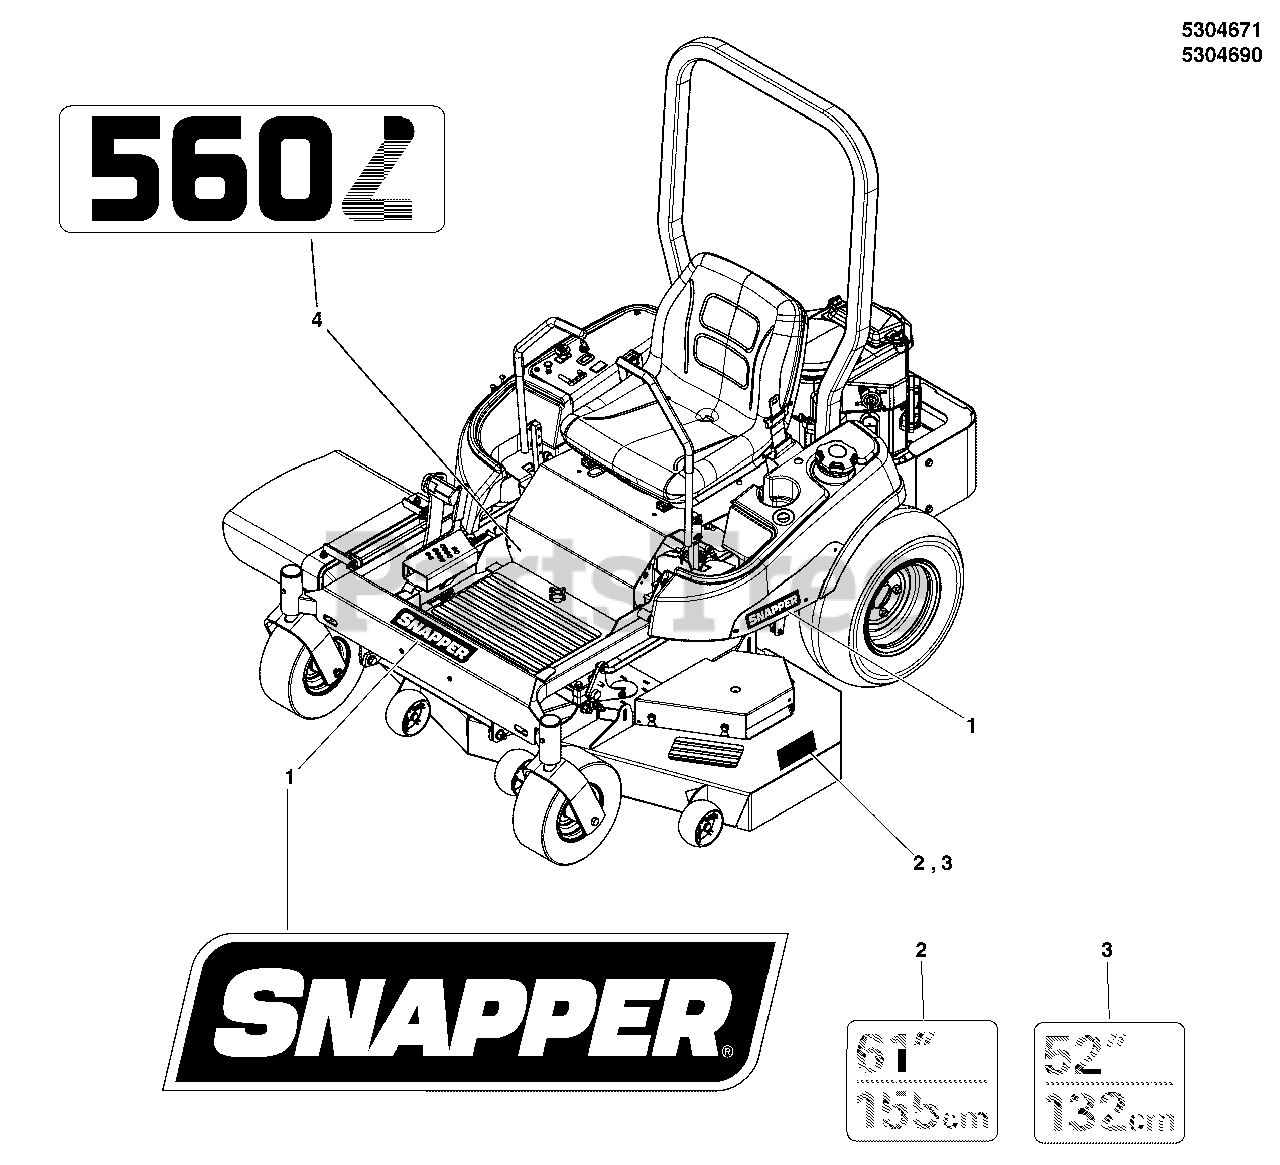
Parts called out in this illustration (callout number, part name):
1	DECAL, Logo, Snapper
2	DECAL, MOWER WIDTH 61IN/155CM
3	DECAL, MOWER WIDTH 52IN/132CM
4	DECAL, MODEL SERIES, 560Z
